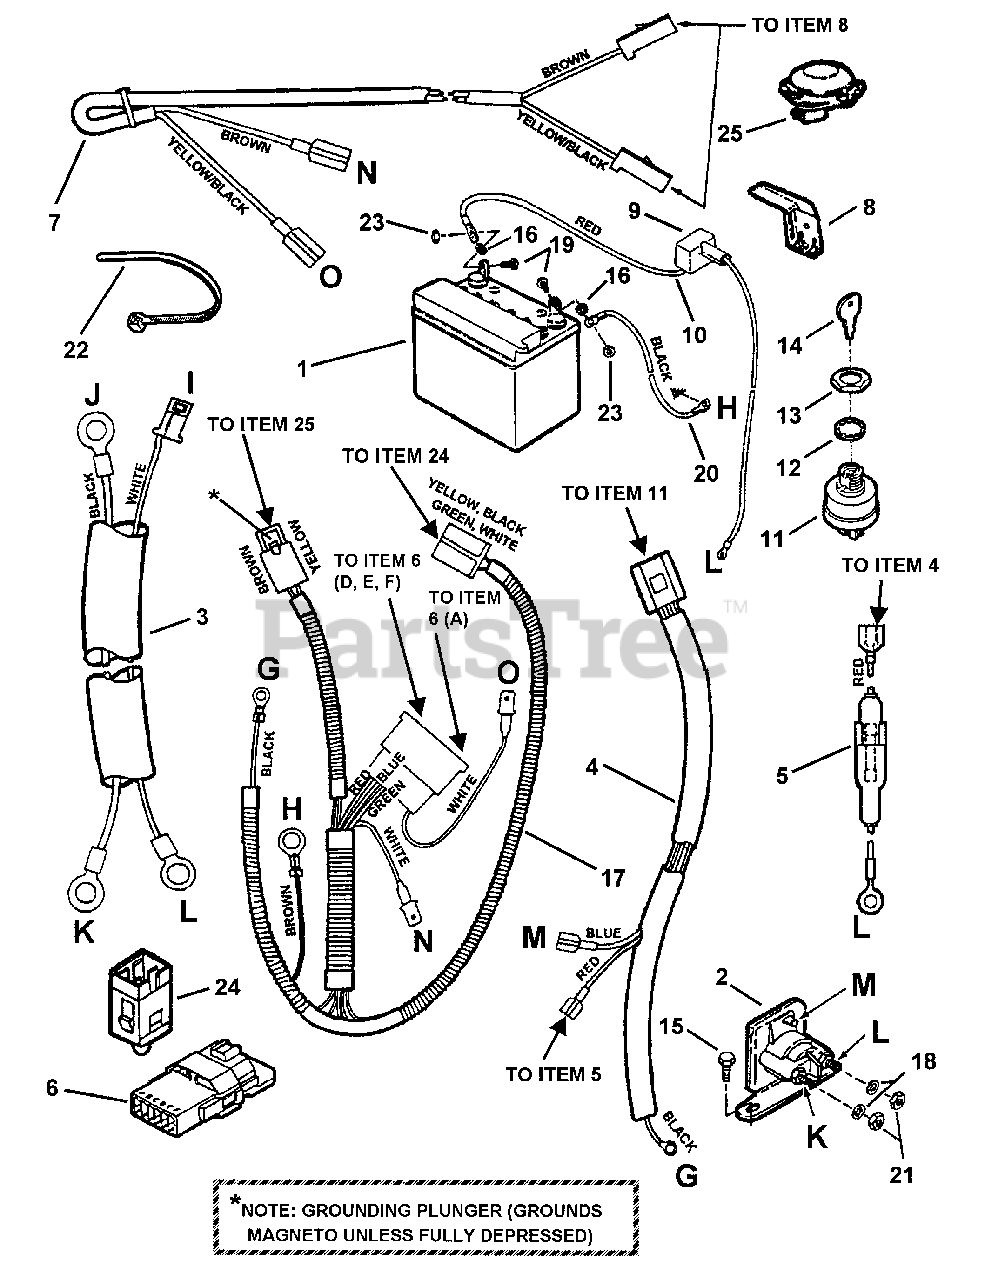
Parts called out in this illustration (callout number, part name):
1	KIT, Battery, 12V, U-1-7RS, 220CCA Dry Charge Snapper No Spill
2	SOLENOID
3	HARNESS, Starter Wiring
4	HARNESS, Ignition Wiring
5	HOLDER, Fuse
6	INTERLOCK Module
7	HARNESS, Deck Interlock Wiring
8	SWITCH, Deck Interlock (Normally Open)
9	COVER, Battery Cable
10	CABLE, Positive (Red) (17" Long)
11	SWITCH, Ignition
12	WASHER, 5/8" Internal Tooth Lock
13	NUT, 5/8-32 Hex
14	KEY, Switch
15	SCREW, 1/4-20 x 1/2" Hex Washer Self-Tap
16	RETAINER, 1/4" Bolt
17	HARNESS WIRE (Operator Presence Control)
18	WASHER, 1/4 Internal Tooth Lock
19	SCREW, 1/4-20 x 5/8" Hex Head Cap, Grade 5
20	CABLE, Negative (15" Long)
21	NUT, 1/4-20 Hex Grade 5 or B
22	TIE, 7" Long Cable
23	NUT, 1/4-20 Hex Center Lock, Grade 5 or B
24	SWITCH, Operator Presence Control (OPC) Traction (NO/NC)
25	SWITCH, Seat (Normally Closed)
